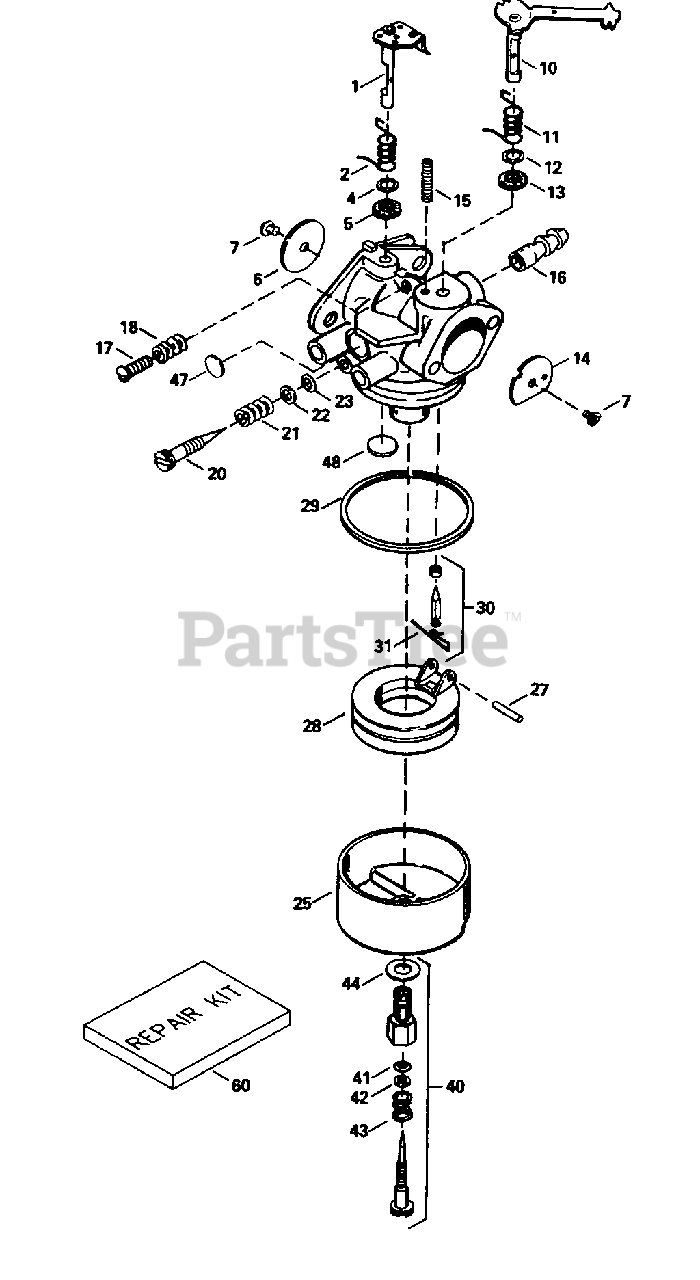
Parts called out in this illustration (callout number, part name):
1	Throttle Shaft & Lever Assembly
2	Throttle Return Spring
4	Dust Seal Washer
5	Dust Seal (Throttle)
6	Throttle Shutter
7	Shutter Screw
10	Choke Shaft & Lever Assembly
11	Choke Return Spring
12	Dust Seal Washer
13	Dust Seal (Choke)
14	Choke Shutter
15	Choke Positioning Spring
16	Fuel Fitting
17	Throttle Crack Screw/Idle Speed Screw
18	Tension Spring
20	Idle Mixture Screw
21	Tension Spring
22	Idle Mixture Screw Washer
23	Idle Mixture Screw "O"-Ring
25	Float Bowl
27	Float Shaft
28	Float
29	Float Blow "O"-Ring
30	Inlet Needle, Seat & Clip
31	Spring Clip
40	Main Adj. Screw Ass'y.
41	High Speed Mixture Screw "O"-Ring
42	High Speed Mixture Screw Washer
43	High Speed Mixture Screw Tension Spring
44	Bowl Nut Washer
47	Welch Plug, Idle Mixture Well
48	Welch Plug, Atmospheric Vent
60	Repair Kit
